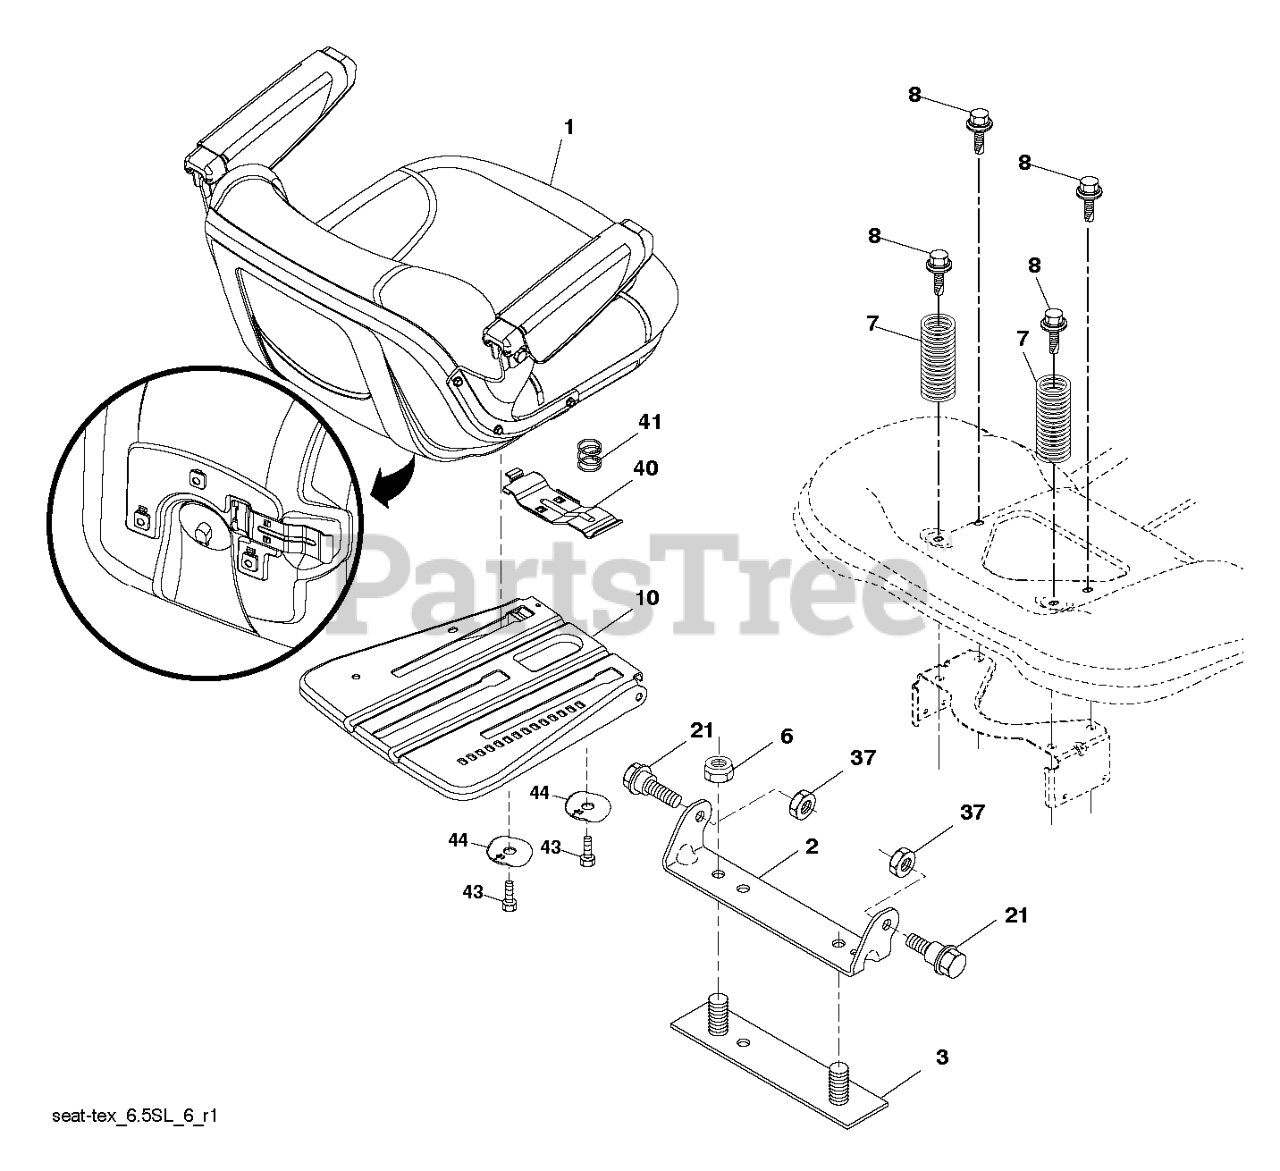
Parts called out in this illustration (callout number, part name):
1	SEAT.TH154.498GY.HUS.ARMRESTS
2	BRKT.PIVOT.FENDER
3	STRAP
6	NUT
7	SPRING.COMPRESS.SEAT.TAPERED
8	BOLT.5/16-18UNCX3/4 W/SEMS.BLK
10	PLATE.PNT.SEAT.SLIDE.3PT.EDIP
21	BOLT.5/16-18X5/8.SHOULDER
37	NUT.71038.31-18.HEX.NYLOCK
40	HANDLE.SLIDE.SEAT.TEX.GREY
41	SPRING.LATCH.SEAT.TEX
44	WASHER.WINGED.3/8ID.1.5OD
